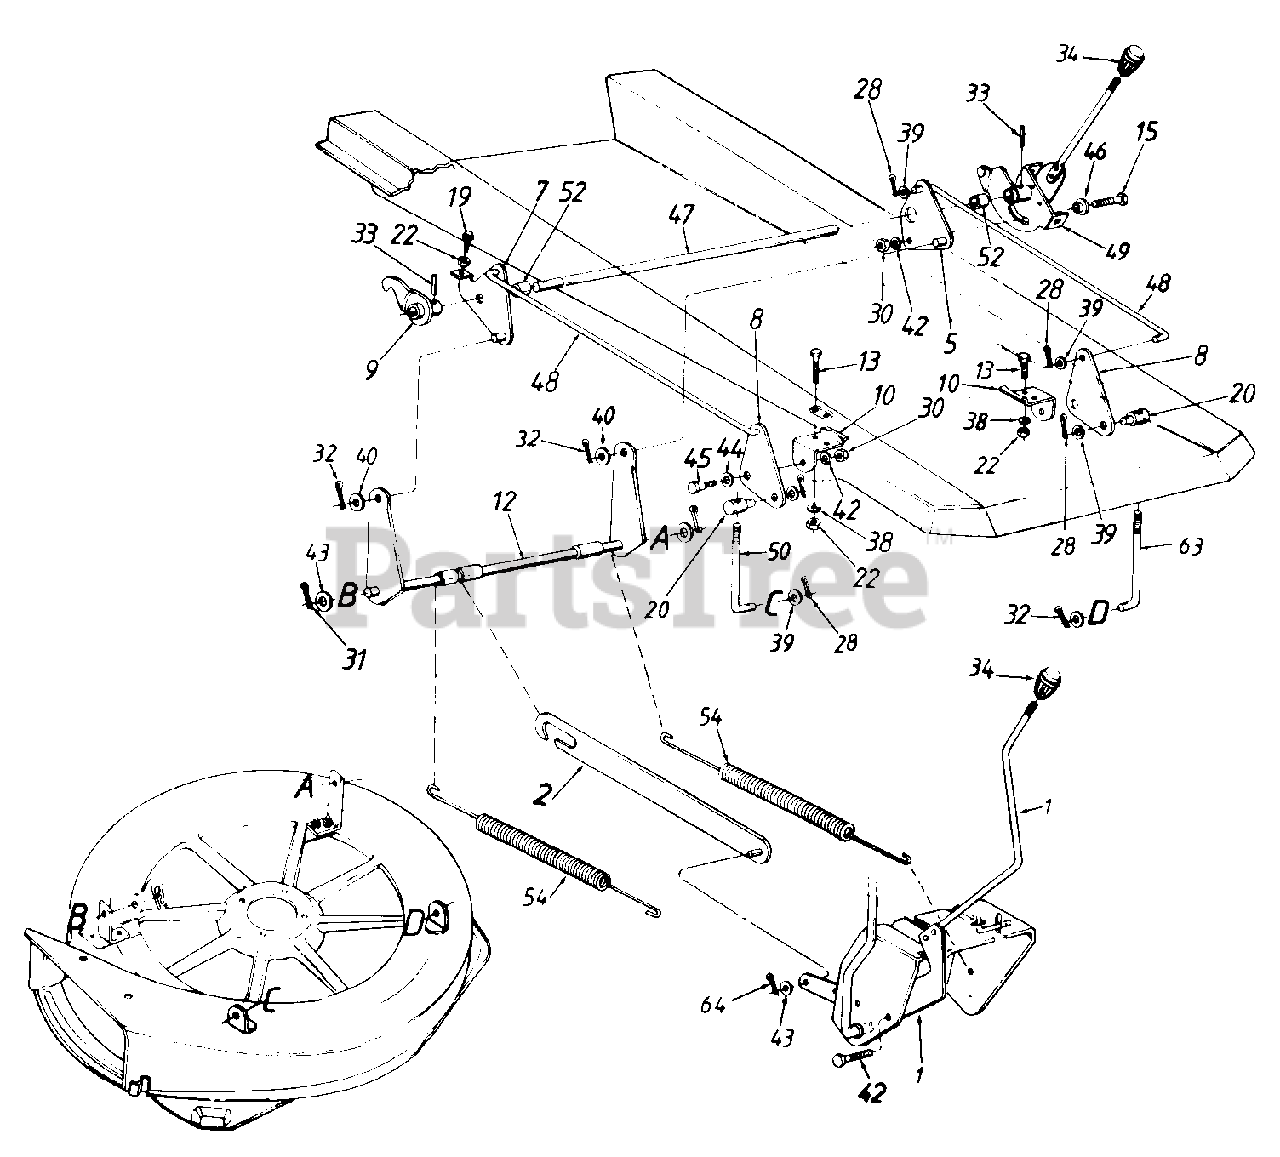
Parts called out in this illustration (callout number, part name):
7	Deck Lift Brkt. Ass'y.
8	Deck Lift Bracket
9	Deck Lift Float Brkt Ass'y.
10	Deck Lift Pivot Brkt.
15	Hex Bolt 3/8-16 x 1"
19	Hex Wash.-Tap Scr. 5/16-18 x 1.25" Lg.
20	Ferrule
22	Hex Nut 5/16-18 Thd.
28	Cotter Pin 3/32" Dia.
30	Hex Nut 3/8-16 Thd.
31	Internal Cot. Pin 1/2" Dia.
32	Int. Cot. Pins 3/8" Dia.
33	Spring Pin Spir. 1/4" Dia.
34	Knob
38	L-Wash 5/16" I.D.
39	Fl-Wash. .385 I.D. x.62
40	Fl-Wash. .635 I.D. x 1.12
42	L-Wash. 3/8" I.D.
43	Fl-Wash. .385 I.D. x .87 0. D.
44	Spring Washer.530 I.D.
45	Shld. Bolt.500" Dia. x.215"
46	Shld. Spacer.625" I.D.
47	Rear Hgt. Adj. Shaft
50	J-Bolt 3/8-24 x 5.25" Lg.
52	Spacer.885 I.D.
54	Ext. Spring 13.25" Lg.
63	J-Bolt 3/8-24 x 5.4" Lg.
64	Cotter Pin 1/8" Dia.
